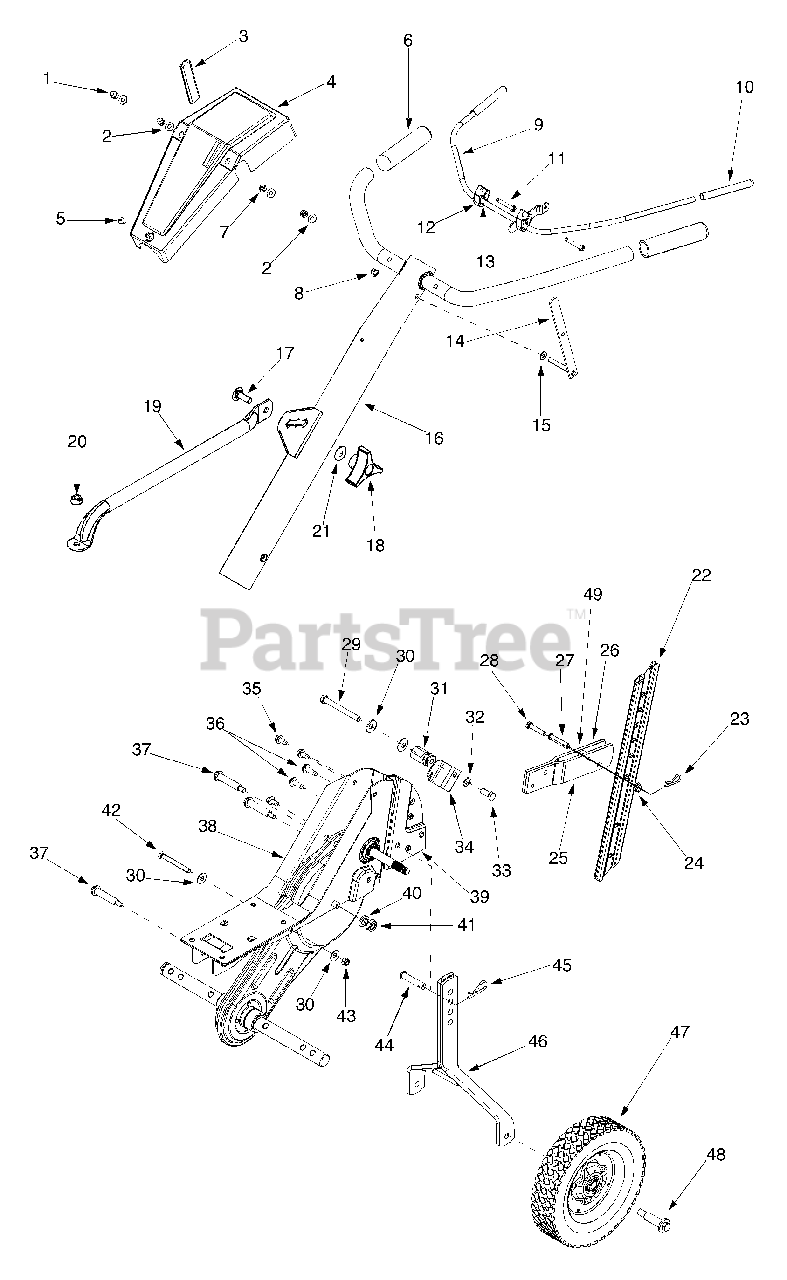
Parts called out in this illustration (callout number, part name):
1	Acorn Lock Nut 1/4-20
2	Flat Washer .271" I.D. x .630" O.D.
3	Reverse Handle Grip
4	Handle Cover w/o throttle
5	Truss Mach. Scr. #10 x 1/2" Lg.
7	Hex Nut 1/4-20 Gr.2
8	Cap Speed Nut
11	Hex Bolt 1/4-20 x 2.25" Lg. Gr.5
12	Clutch Handle Holder
13	Flat Washer .385" I.D. x .62" O.D.
15	Flat Washer .344" I.D. x .62" O.D.
21	Bell. Wash. .34" I.D.
24	Hex Flange L-Nut 5/16-18 Thd. Gr.5
28	Hex Bolt 5/16-18 x 1.5" Lg.
29	Hex Bolt 5/16-18 x 3" Lg.
30	Wash. Bell. .340" I.D. x .872" O.D.
31	Spec. Hex Nut
32	L-Wash. 5/16" I.D.
33	Hex Bolt 5/16-18 Gr. 5
35	Hex Washer Screw 5/16-18 x .62" Lg.
36	Hex Wash. Hd. TT-Tap Scr.
37	Shdl. Bolt 5/16-18
40	Lock Washer 7/16
41	Jam Nut 7/16-20 Gr. 2
42	Hex Bolt 5/16-18 x 2.75" Lg.
43	Hex Nylon Nut 5/16-18 Thd.
47	Wheel Ass'y 8" x 1.75"
48	Shoulder Screw .496 I.D. x 1.445 O.D.
